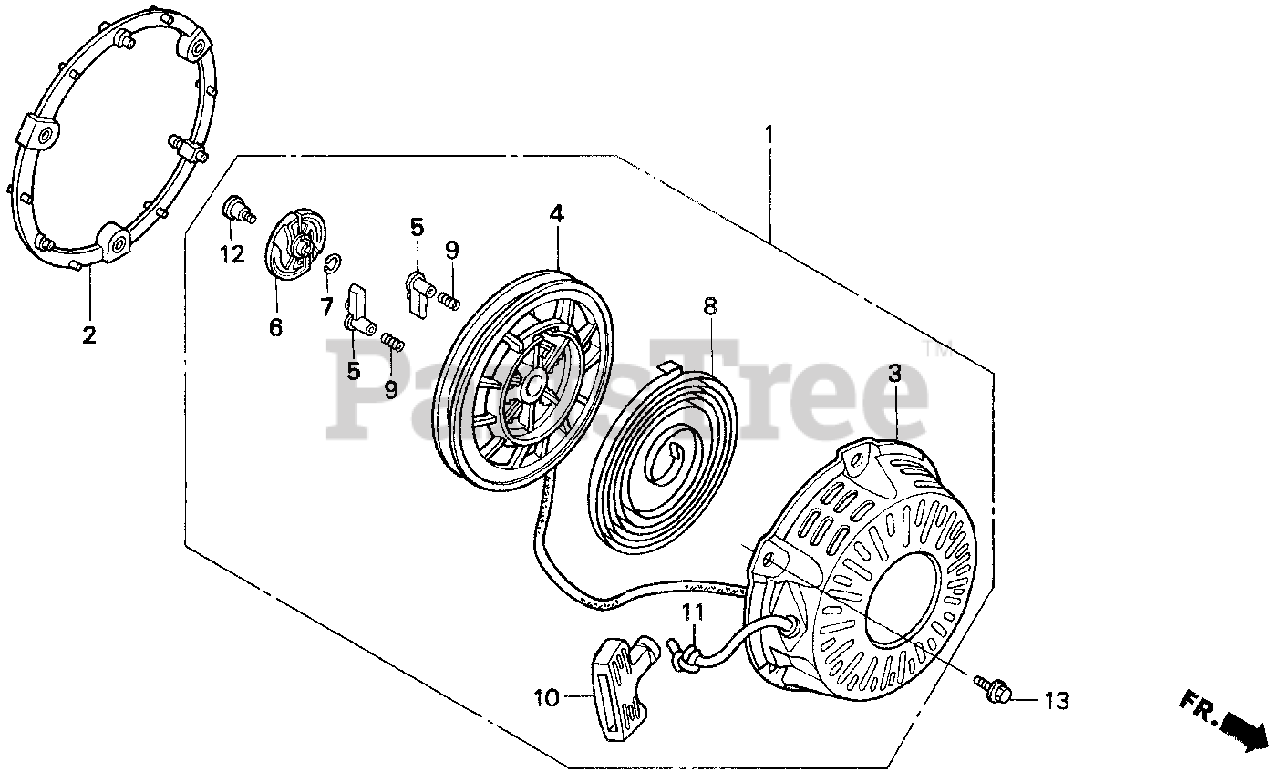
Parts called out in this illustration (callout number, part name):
1	STARTER ASSY., RECOIL *R8* (BRIGHT RED)
1	STARTER ASSY., RECOIL *NH1* (BLACK)
2	SPACER, RECOIL STARTER MOUNTING *NH1* (BLACK)
2	SPACER, RECOIL STARTER MOUNTING *R8* (BRIGHT RED)
3	CASE, RECOIL STARTER *R8* (BRIGHT RED)
3	CASE, RECOIL STARTER *NH1* (BLACK)
4	REEL, RECOIL STARTER
5	RATCHET, STARTER
6	GUIDE, RATCHET
7	SPRING, FRICTION
8	SPRING, RECOIL STARTER
9	SPRING, RETURN
10	KNOB, RECOIL STARTER
11	ROPE, RECOIL STARTER (NA USE ALT:08550-ZG921-11)
12	SCREW, SETTING
13	BOLT, FLANGE (6X18)
